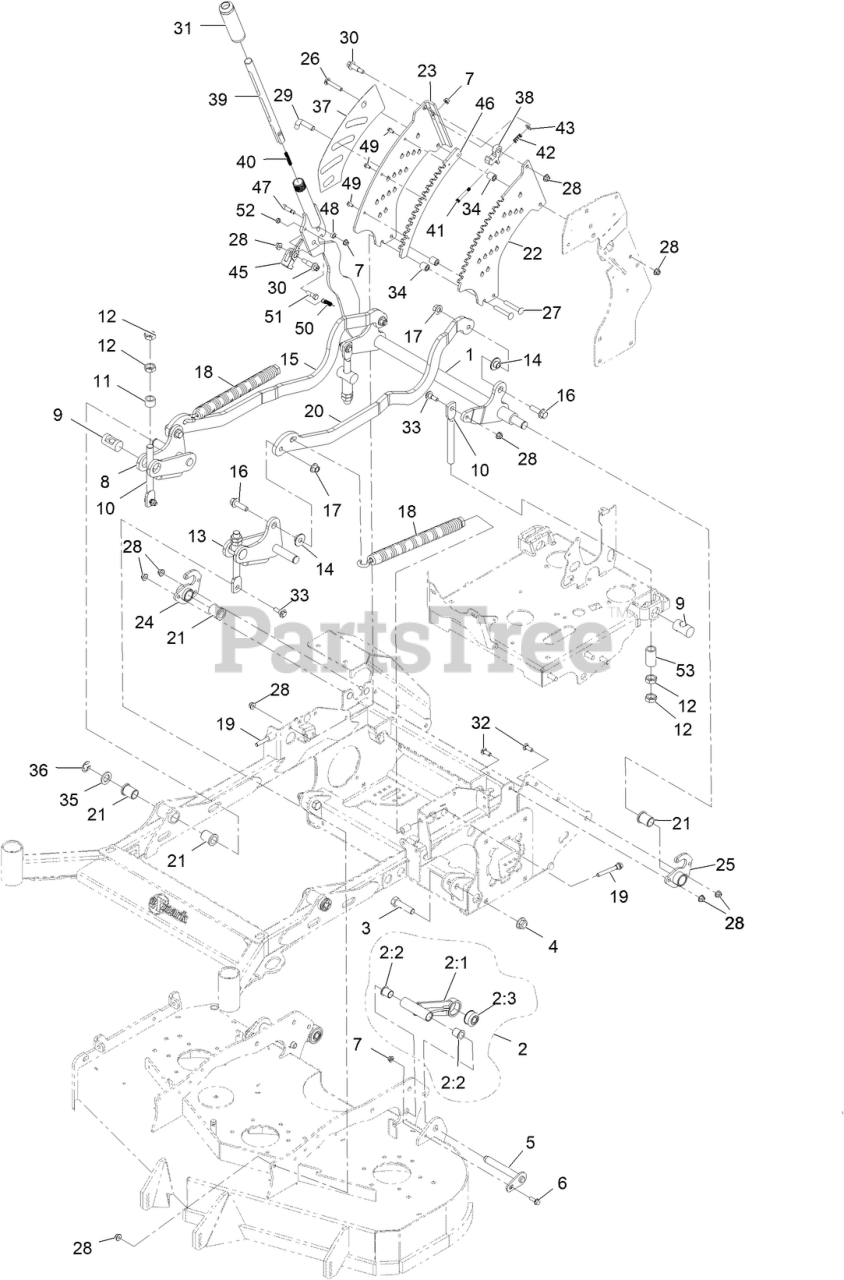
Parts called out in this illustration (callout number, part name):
1	CROSS SHAFT-DECKLIFT-REAR [BLACK]
2	ASM-DECK STRUT W/BUSHINGS
2:1	ASM-Deck Strut
2:2	BUSHING-IGUS FLNG .75X1
2:3	Bushing
3	SCREW-HH
4	NUT-FLNG 5/8-18 CTRLOCK GR G
5	ASM-DECK STRUT PIN
6	SCREW-HHF
7	NUT-HF, NI
8	Weld-Arm-Decklift-Front-RH
9	TRUNION-DECK LIFT
10	LINK-DECKLIFT
11	SPACER-DECKLIFT
12	NUT-JAM
13	Weld-Arm-Decklift-Front-LH
15	LINK-DECKLIFT-RH
16	SCREW-HHF
17	Nut-Lock 1/2-13
18	SPRING-EXTENSION
19	BOLT-SHOULDER
20	LINK-DECKLIFT-LH
21	BUSHING-FLANGED
22	Plate-Inner-HOC
23	Plate-Outer-HOC
24	SUPPORT-HOC SHAFT RH
25	SUPPORT-HOC SHAFT LH
26	BOLT-CARR, SHORT NECK
27	SCREW-CARR
28	NUT-HF, NI
29	PIN-HOC
30	BOLT-SHOULDER
31	GRIP-HANDLE-DECKLIFT
32	SCREW-CARR
33	SCREW-SHOULDER, HHF
34	SPACER-HOC
36	RING-RETAINING, EXT
37	DECAL-HEIGHT OF CUT
38	PAWL-DECKLIFT
39	PLUNGER-TOP
40	SPRING-COMPRESSION
41	SCREW-SHOULDER-CAP
42	SPRING-COMPRESSION
45	Pawl-Lock-Decklift
46	Plate-Doubler-HOC-Lock
47	BOLT-SHOULDER
49	SCREW-HWH
50	SPRING-EXTENSION
51	BOLT-SHOULDER
52	NUT-LOCK, NI
53	SPACER 1.13 O.D. X .81 I.D. X 2.05L
